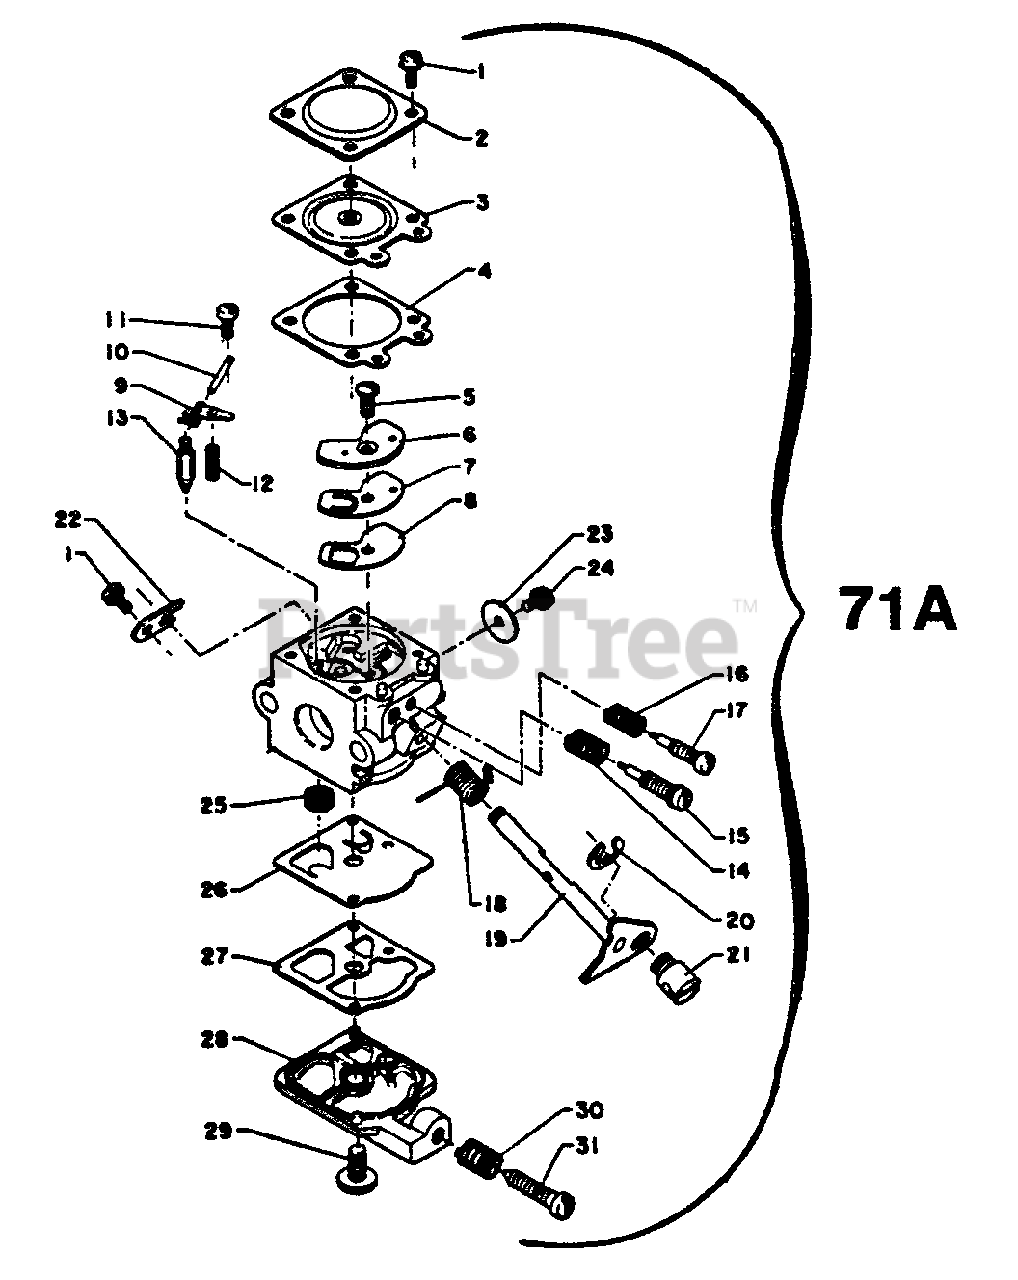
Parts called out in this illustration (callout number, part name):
2	COVER, METERING
3	DIAPHRAGM, METERING
4	GASKET, METERING
5	SCREW, CIRCUIT PLATE
6	PLATE, CIRCUIT
7	VALVE, CHECK
8	GASKET, CIRCUIT PLATE
9	LEVER, METERING
10	PIN, METERING LEVER
11	SCREW, METERING LEVER PIN
12	SPRING, METERING LEVER
13	VALVE, INLET NEEDLE
15	NEEDLE - HIGH SPEED
16	SPRING, IDLE ADJUST
17	NEEDLE - LOW SPEED
18	SPRING, THROTTLE RETURN
19	SHAFT, THROTTLE
20	RING, RETAINING
22	CLIP, THROTTLE SHAFT
23	VALVE, THROTTLE
25	STRAINER
26	DIAPHRAGM, PUMP
27	GASKET, PUMP
28	COVER, PUMP
29	SCREW, PUMP COVER
30	SPRING, IDLE ADJUST
31	SCREW, IDLE ADJUST
71A	CARBURETOR WA-59
